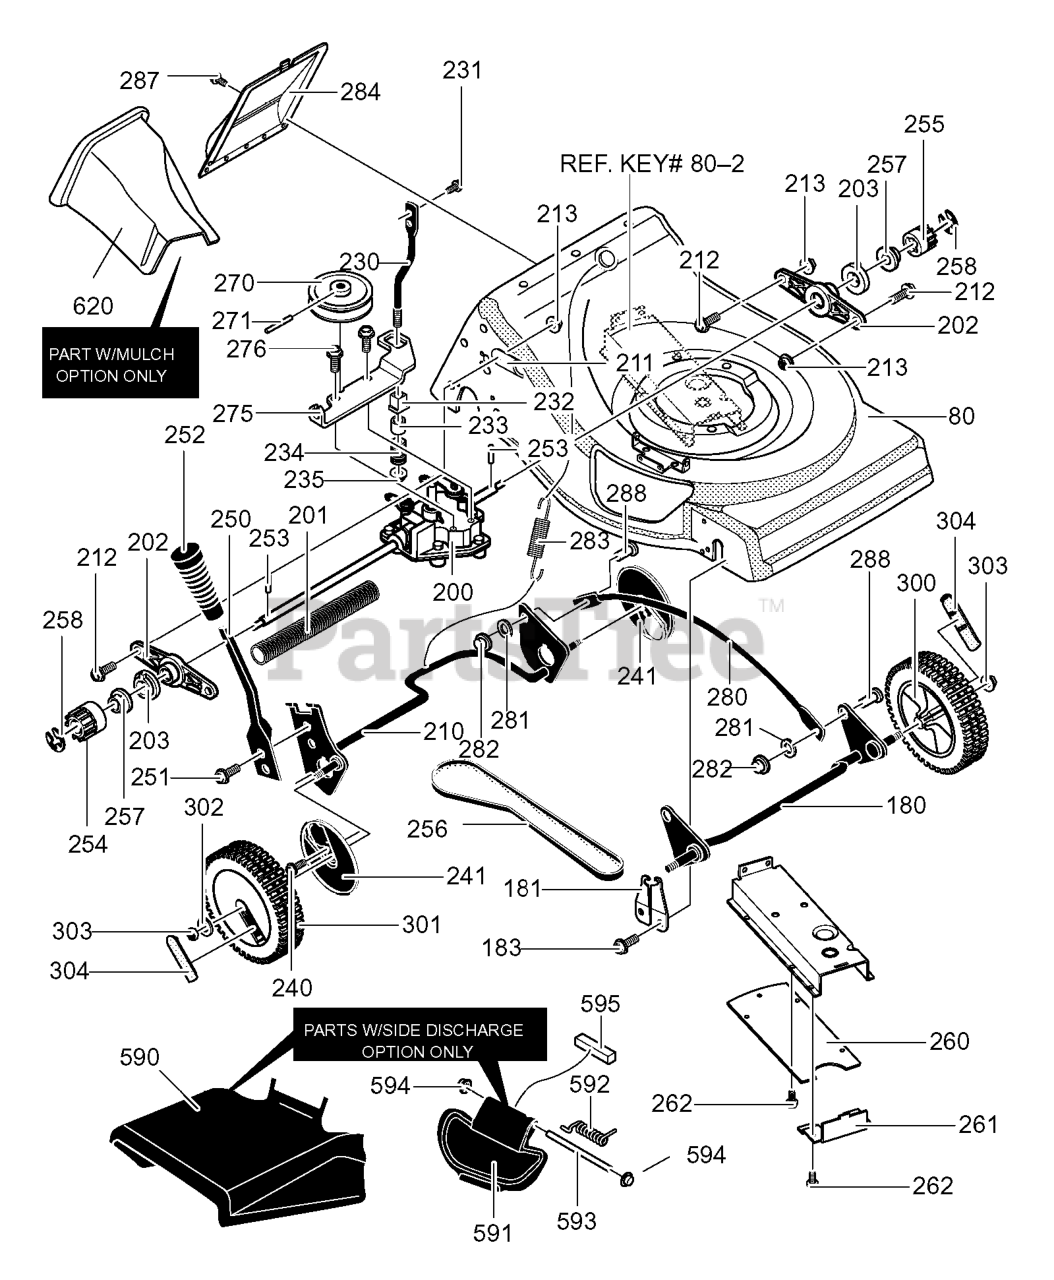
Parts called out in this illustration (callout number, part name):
80	Assy., Frame
180	Assy., Crossbar Front
181	Bushing, Front
183	Screw, 1/4-14x.50
200	Transmission
201	Shield, Axle
202	Support, Axle
203	Bearing, Lifter
210	Assy., Crossbar RR
211	Retainer, Bearing
212	Screw, 5/16-18 x 0.75
213	Nut, 5/16-18Wdfllk
230	Support, Spring
231	Screw, 1/4-20x.63
232	Bushing, Spring
234	Spring, Compression
235	Nut, 5/16-18 Wdfllk
240	Screw, 1/4-14x.50
241	Dust Cover
250	Lever, Spring
251	Screw, 1/4-20x.63
252	Knob, Hgt Adjust
253	Pin, Drive
254	Gear, Pinion Right
255	Gear, Pinion Left
256	Belt, 2L 15.75L
257	Flatwasher
258	Ring, Ret. E
260	Cover, Lower Belt Guard
261	Cover, Front Belt
262	Screw, 10-16x.50
270	Pulley, 2L
271	Pin, Spring
275	Bracket, Transaxle
276	Screw, 1/4-20x.50
280	Link, Lifter
281	Nut, Push On
282	Cap, Push On
283	Spring, Ext.
284	Cover, Rear Trans.
287	Screw, 1/4-20x.63
288	Pin, Clevis
300	Tire & Rim
301	Wheel, Drive
302	Washer, Flat
303	Nut, 3/8-16
304	Hub Cap
